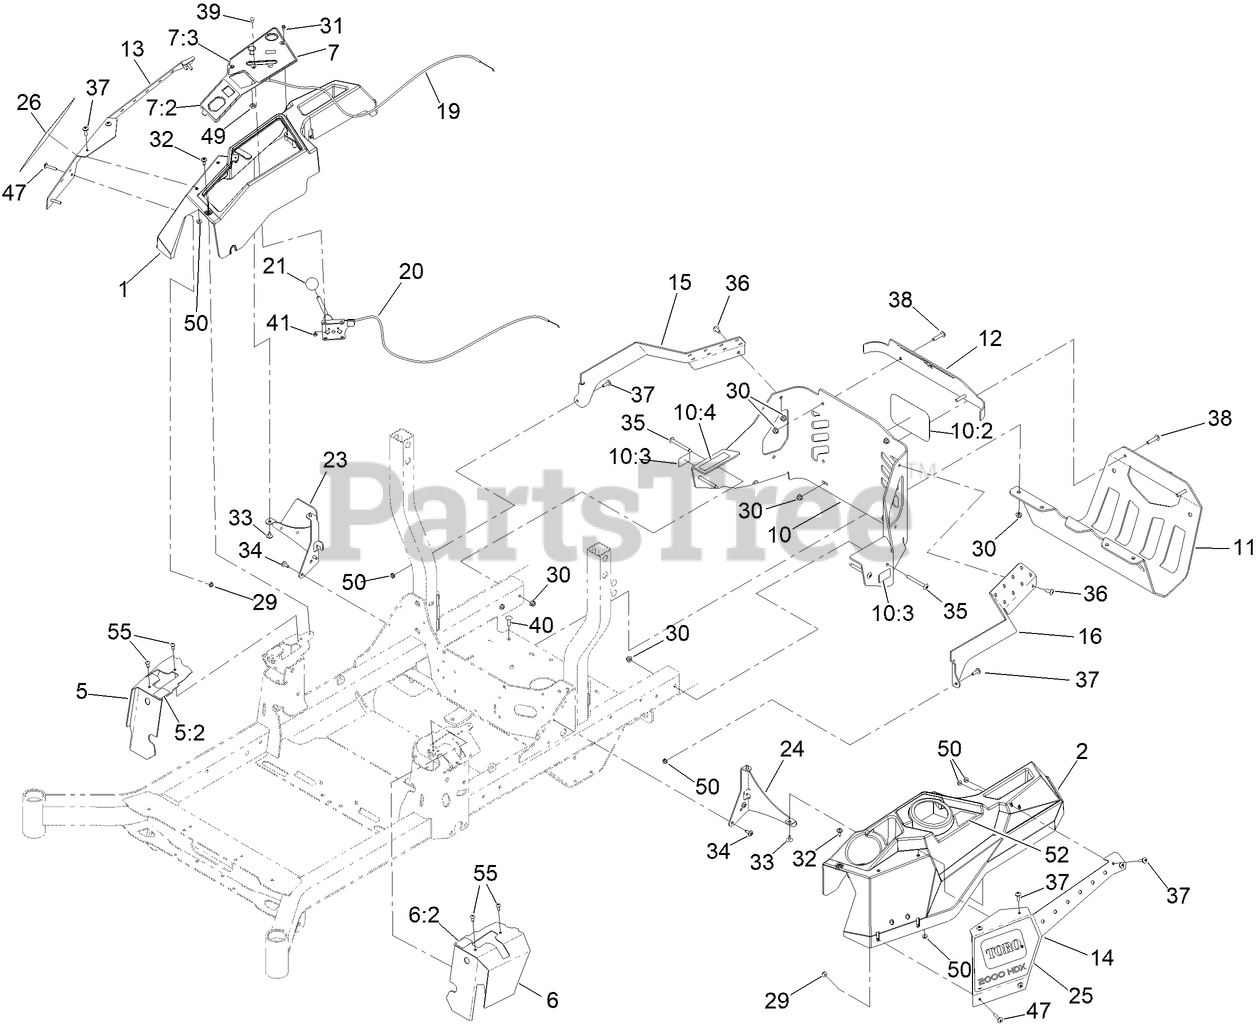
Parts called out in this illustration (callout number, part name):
1	CONSOLE-RH
2	CONSOLE-LH
5	COVER - CONTROL, MOTION
5:2	DECAL-MOTION CONTROL
6	COVER - CONTROL, MOTION
6:2	DECAL-MOTION CONTROL
7	CTRL PANEL ASM
7:2	DECAL-PANEL, CONTROL
7:3	DECAL-PANEL CTRL
10	REAR GUARD ASM
10:2	DECAL
10:3	DECAL-WARNING
10:4	DECAL-ARRESTOR, SPARK
11	GUARD-MUFFLER [BLACK]
12	TRIM-UPPER REAR
13	COVER,POD RH
14	COVER [BLACK]
15	BRACKET-GUARD, RH
16	BRACKET-GUARD, LH
19	CABLE-CONTROL, CHOKE
20	CABLE-CONTROL, THROTTLE
21	KNOB-BALL
23	SUPPORT-CONSOLE, RH
24	BRACKET-CONSOLE, LH
25	DECAL - HDX
26	DECAL - HDX
29	NUT-HF
30	NUT-HF, NI
31	SCREW-HWH
32	SCREW-SHOULDER
33	SCREW-TORX
34	SCREW-TORX
35	SCREW-TORX
36	SCREW-TORX
37	SCREW-TRUSS
38	SCREW-TORX
39	BOLT-CARR
40	SCREW-CARR
41	NUT-LOCK, NI
47	SCREW-TRUSS
49	NUT-HJ
50	NUT-KEPS
52	DECAL-FILL, FUEL
55	SCREW-TPH THD FORM
